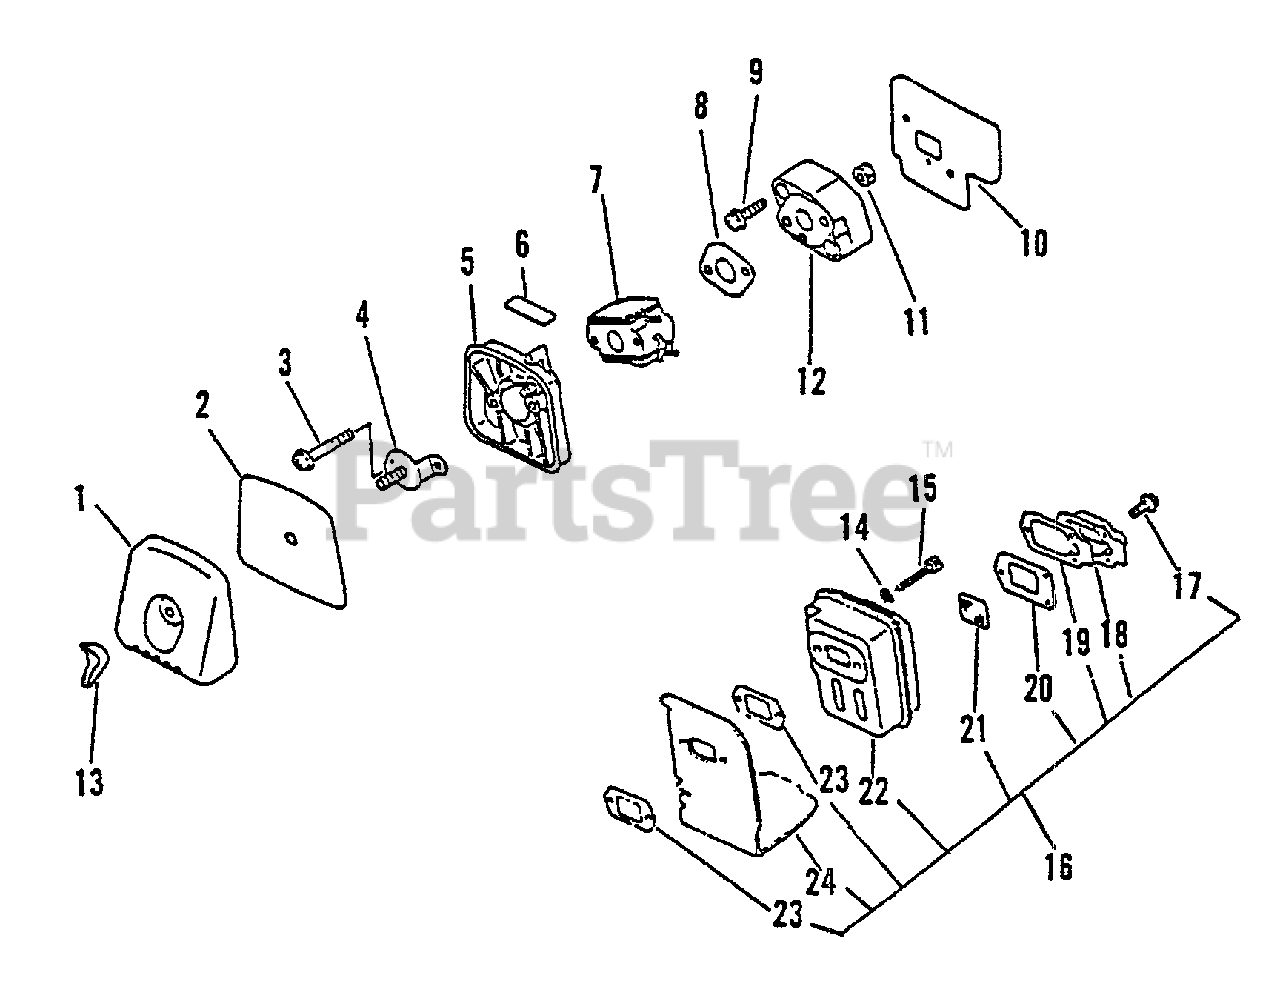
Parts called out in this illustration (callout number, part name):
1	COVER, AIR FILTER - BLACK
2	FILTER, AIR
3	SCREW - 5X64
4	PLATE, PREVENT
5	AIR FILTER CASE ASSY
6	LABEL - CHOKE
7	CARBURETOR C1U-K26
8	GASKET, INTAKE
9	SCREW - 5X22
10	GASKET, INTAKE
12	INSULATOR, INTAKE
13	WINGNUT - 6
14	WASHER - 5
15	SCREW - 5X55
16	MUFFLER ASSY
17	SCREW - 4X10
18	GASKET, EXHAUST - INNER
19	GUIDE, EXHAUST - INNER
20	GASKET, EXHAUST
21	SCREEN, SPARK ARRESTOR
23	GASKET, EXHAUST
24	SHIELD, EXHAUST
